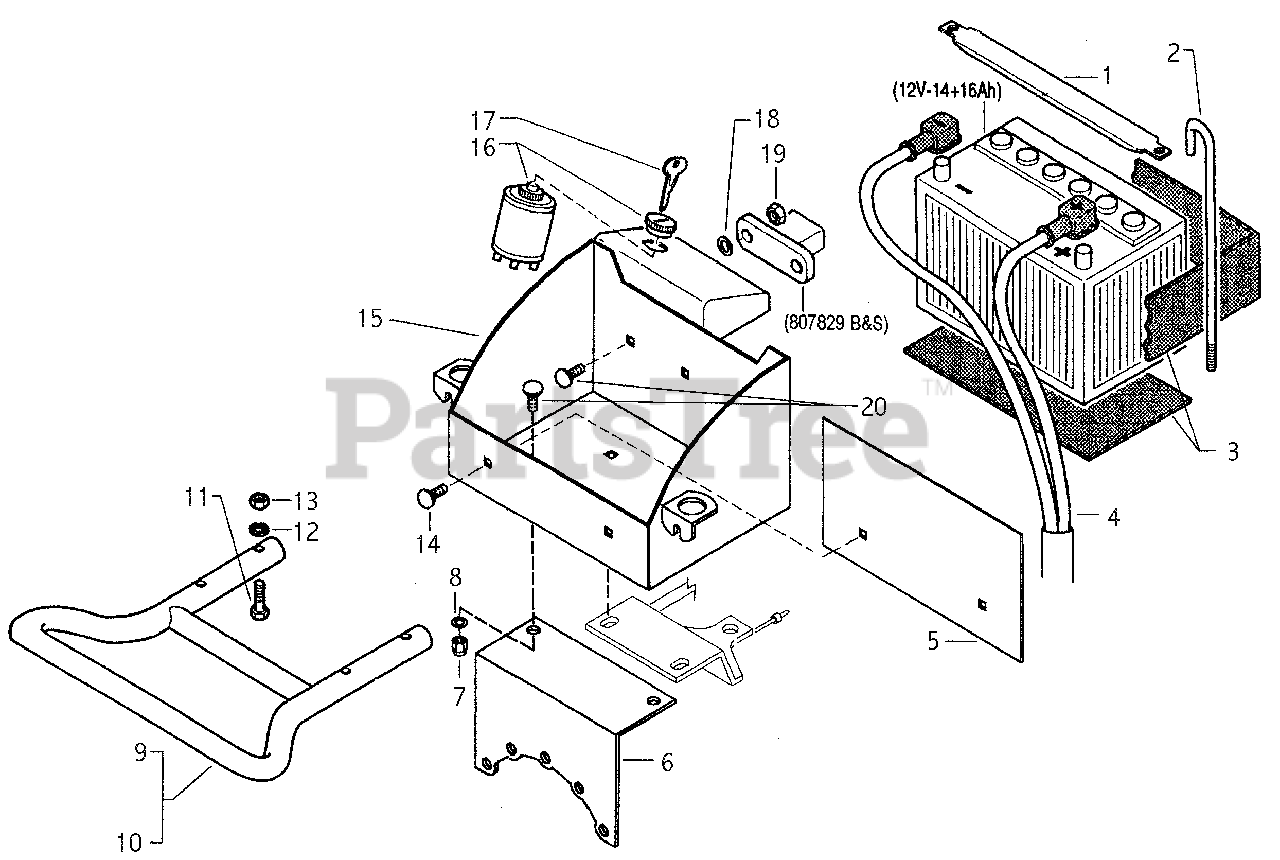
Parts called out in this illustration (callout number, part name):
1	BATTERY BRACKET
2	BATTERY TIEROD
3	BATTERY PADS
4	ELECTRIC START CABLES 5HP
9	BUMPER , INTEK ENGINES"
10	BUMBER, HONDA 5HP"
11	SCREW M8X60
12	FLAT WASHER 8.4
13	NUT, SELF LOCKING M8"
15	BATTERY SUPPORT INTEK
